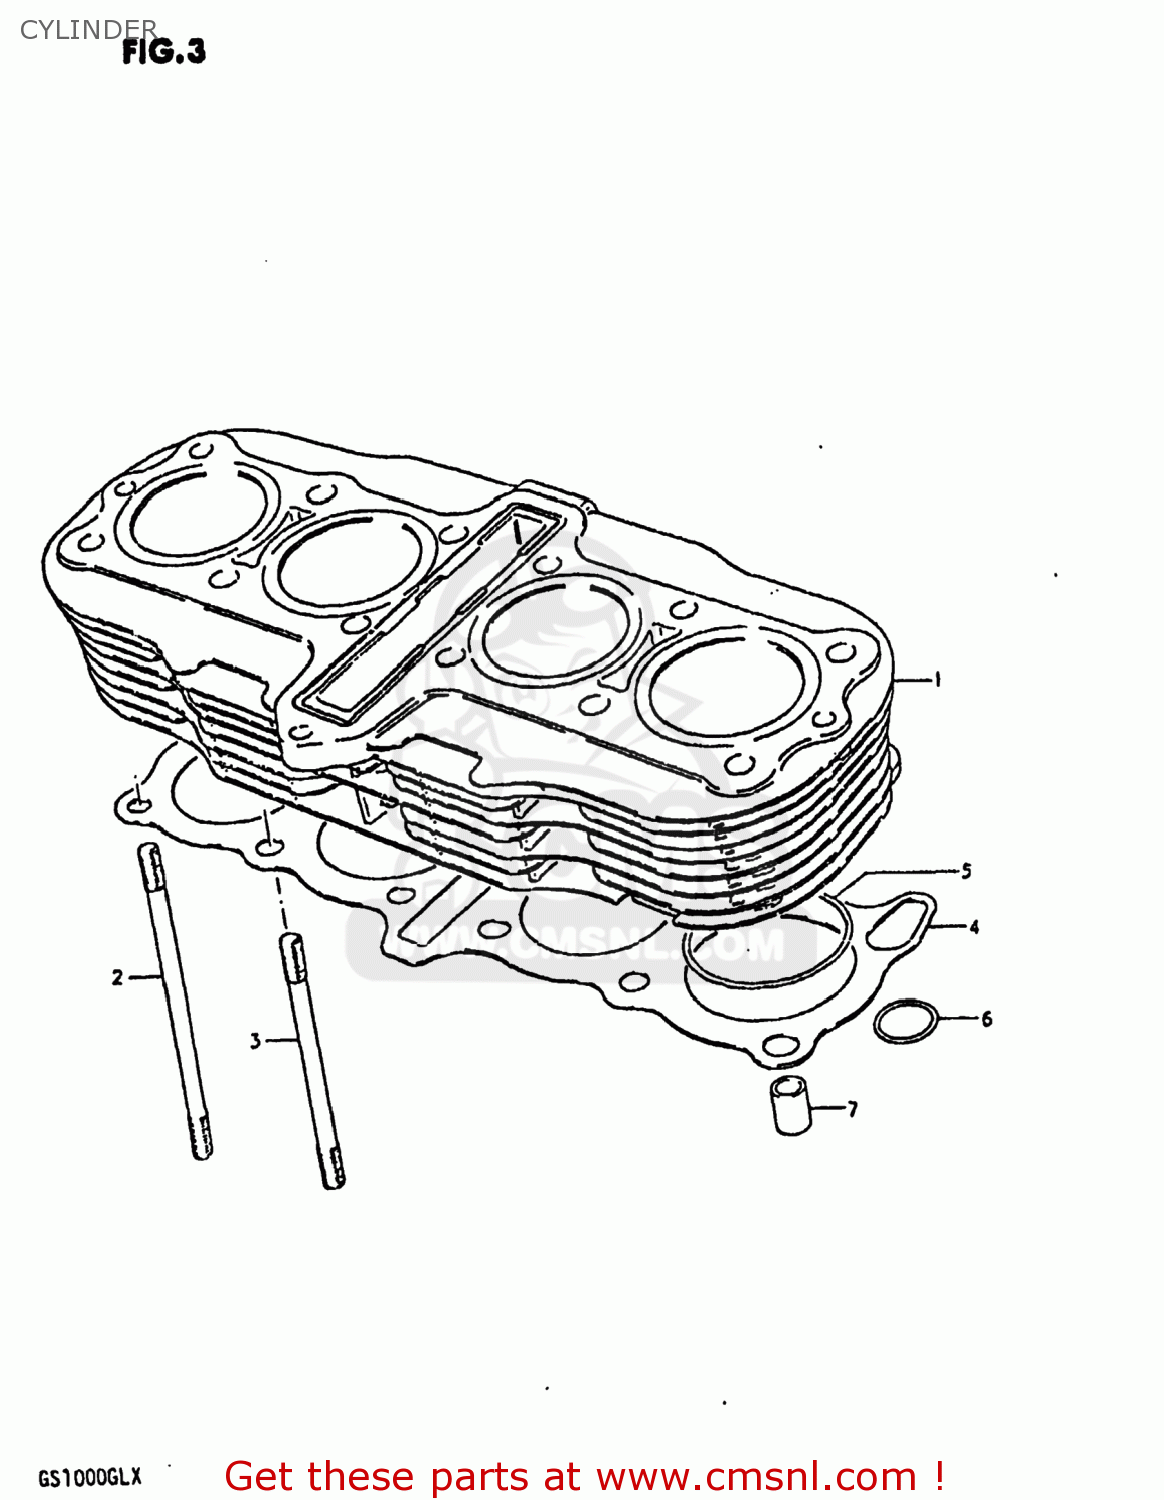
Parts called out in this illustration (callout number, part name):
1	CYLINDER
2	BOLT,STUD
3	STUD
4	GASKET,CYLINDER (MCA)
5	O RING(D:2,ID:74)
6	O RING(D:3.05)
7	PIN
